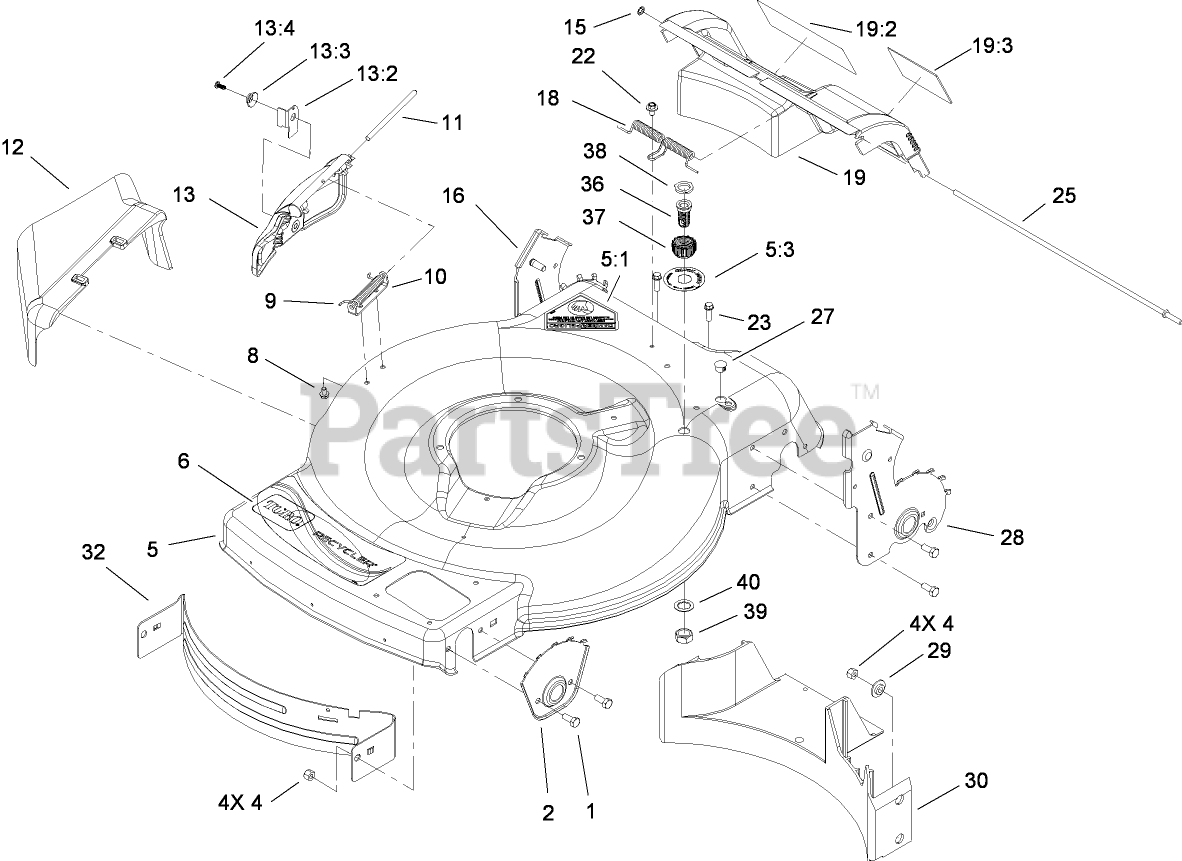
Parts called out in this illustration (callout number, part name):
1	SCREW-HH
4	NUT-LOCK, NI
5	HOUSING ASM
5:1	DECAL-DANGER
5:3	DECAL-PORT, WASHOUT
6	DECAL-RECYCLER (RWD)
8	SCREW-HWH
9	SPRING-TORSION
10	BRACKET-COVER
12	CHUTE-DISCHARGE, SIDE
13	DISCHARGE DOOR ASM
13:2	LATCH-DOOR
13:3	CAP-DOOR
13:4	SCREW-PLASTITE
15	NUT-PUSH
16	8 INCH RH HOC PLATE ASM
18	SPRING-DOOR, REAR
19	REAR DOOR ASM
19:2	DECAL-WARNING
19:3	DECAL-WARNING
22	SCREW AND WASHER ASM
23	SCREW-HWH
25	ROD-PIVOT, REAR DOOR
27	PLUG-DOME
28	8 INCH LH HOC PLATE ASM
29	WASHER-STEPPED
30	BAFFLE-REAR
32	BAFFLE-FRONT
36	PORT-WASHOUT
37	COUPLING-HOSE, WASHOUT PORT
38	WASHER-SEAL, WASHOUT PORT
39	NUT-JAM
40	WASHER-LOCK
